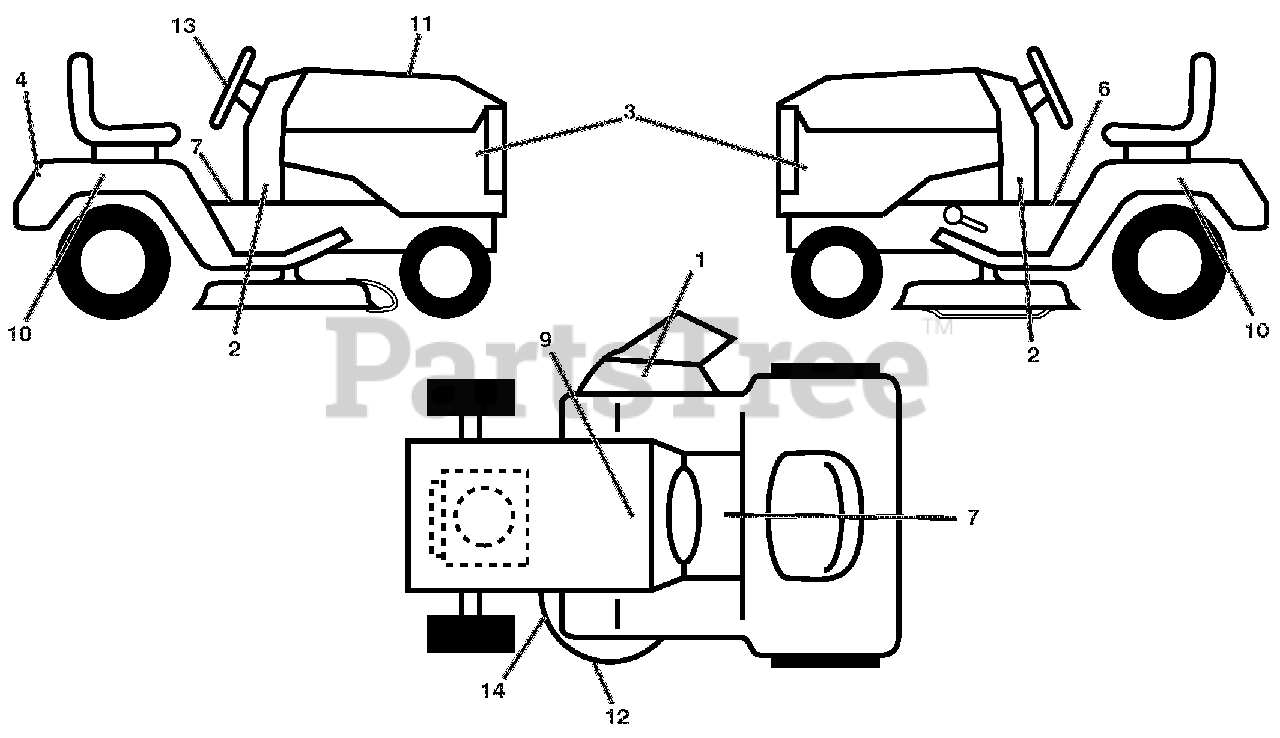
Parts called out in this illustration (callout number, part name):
1	DECAL DECK/DEFLECT. WARNING
2	DECAL LOWER DASH
3	DECAL.SDPNL.PWRDBY KOHL.ARIENS
4	DECAL.FENDER.REAR.ARIENS
6	DECAL, FENDER WARNING
7	DECAL.FENDER
9	DECAL.BAT.DAN/POI P/L SYM.WPN
10	DECAL FENDER SIDE
11	DECAL REPLACEMENT
12	DECAL.MOWER.SCH
13	DECAL.WHEEL.STEER.ARIENS
14	DECAL MOWER CAUTION
